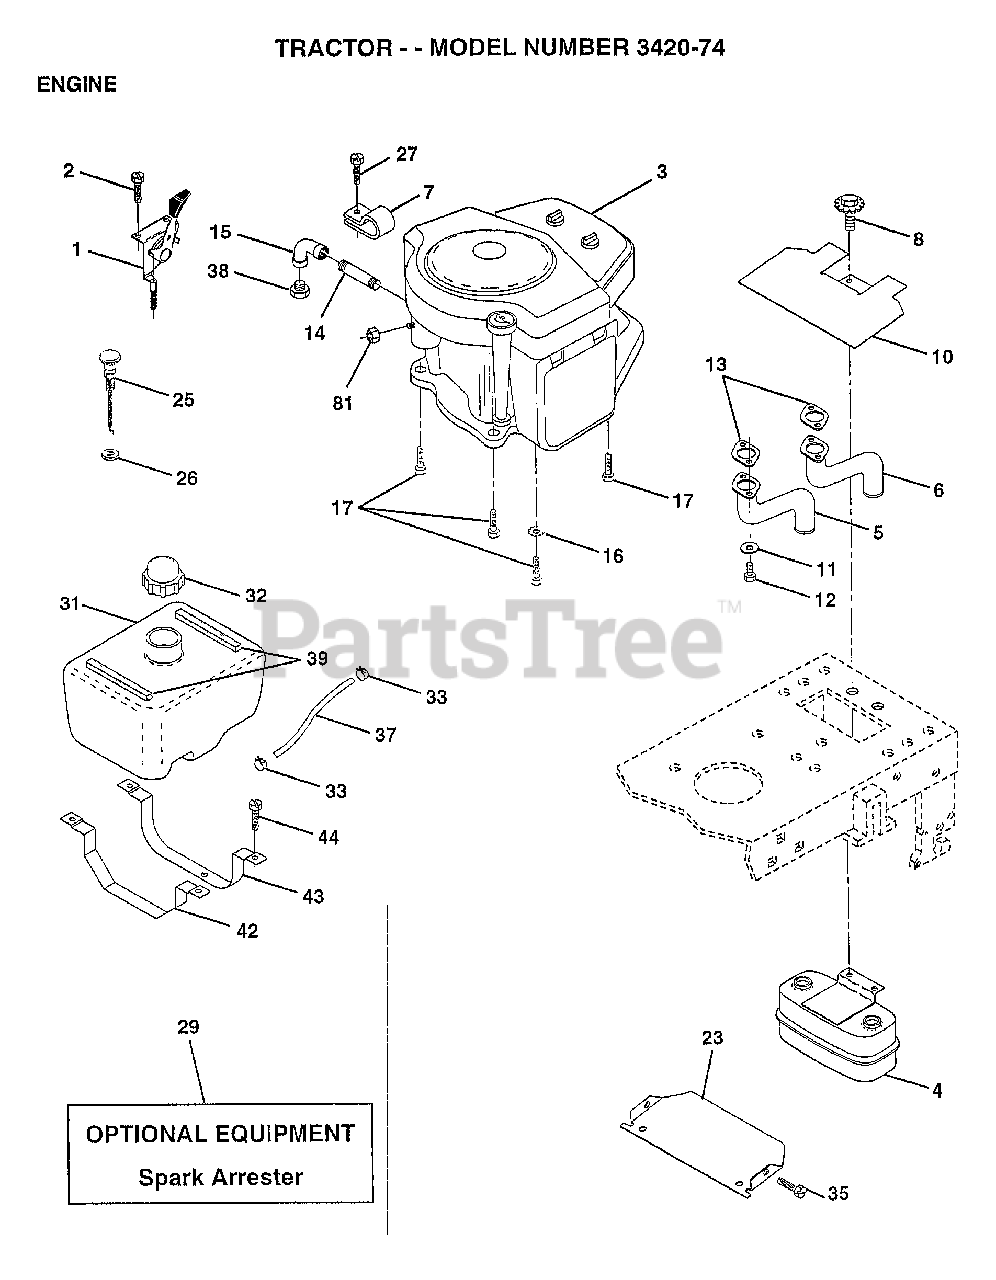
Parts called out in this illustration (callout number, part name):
2	SCREW LT
4	MUFFLER.TW.LOTONE
5	EXHAUST.B&S.18.LH
6	EXHAUST.B&S.18.RH
7	CLAMP.TUBE.DBL.EN
8	BOLT.5/16-18.UNC
10	SHIELD.HEAT.
11	LOCKWASHER
13	GASKET MUFFLER
14	PIPE NIPPLE LT
15	ELBOW
16	LOCKWASHER
17	SCREW LT
23	SHIELD-HEAT
25	"CONTROL.CHOKE.51"""
26	"NUT,KEPS 3/8-24IM"
27	"SCREW-TT,10-32 FL"
31	TANK FUEL 1.9 NAT
32	CAP ASM FUEL
33	HOSE CLAMP
35	SCREW
37	HOSE T
39	"STRIP,FORM"
42	STRAP TANK FUEL
43	STRAP TANK FRONT
44	SCREW
81	NUT
